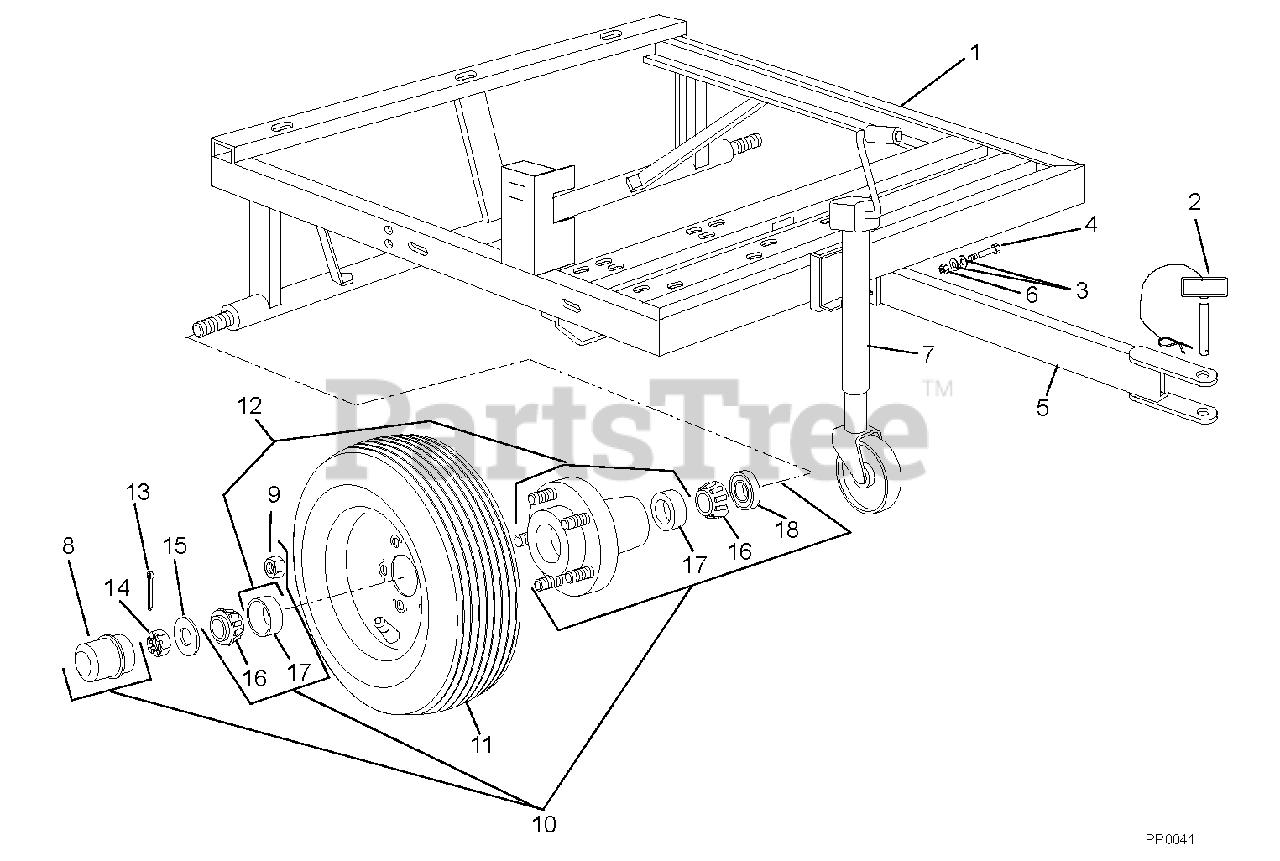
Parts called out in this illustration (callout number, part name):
1	Weldment, Frame
2	Pin, Hitch 1 x 4.50"
3	Washer, Flat Steel .625
4	Cap Screw, Hex Head .625-11 x 3
5	Weldment, Tongue
6	Nut, Nylock .625-11
7	Jack Assembly with Swivel Wheel
8	Cap, Hub
9	Nut, Hex Hub .50-20 UNF 2B-45D
10	Assembly, Hub 5-Bolt (Contains Items 8, 9, 12, 16 and 18)
11	Assembly, Tire & Wheel 18 x 8.5 x 8
12	Hub With Bolts (Includes Item 17)
13	Pin, Cotter .125 x 1.25
14	Nut, Hex .75-16 Castellated
15	Washer .75 Keyed
16	Cone, Bearing
17	Cup, Bearing
